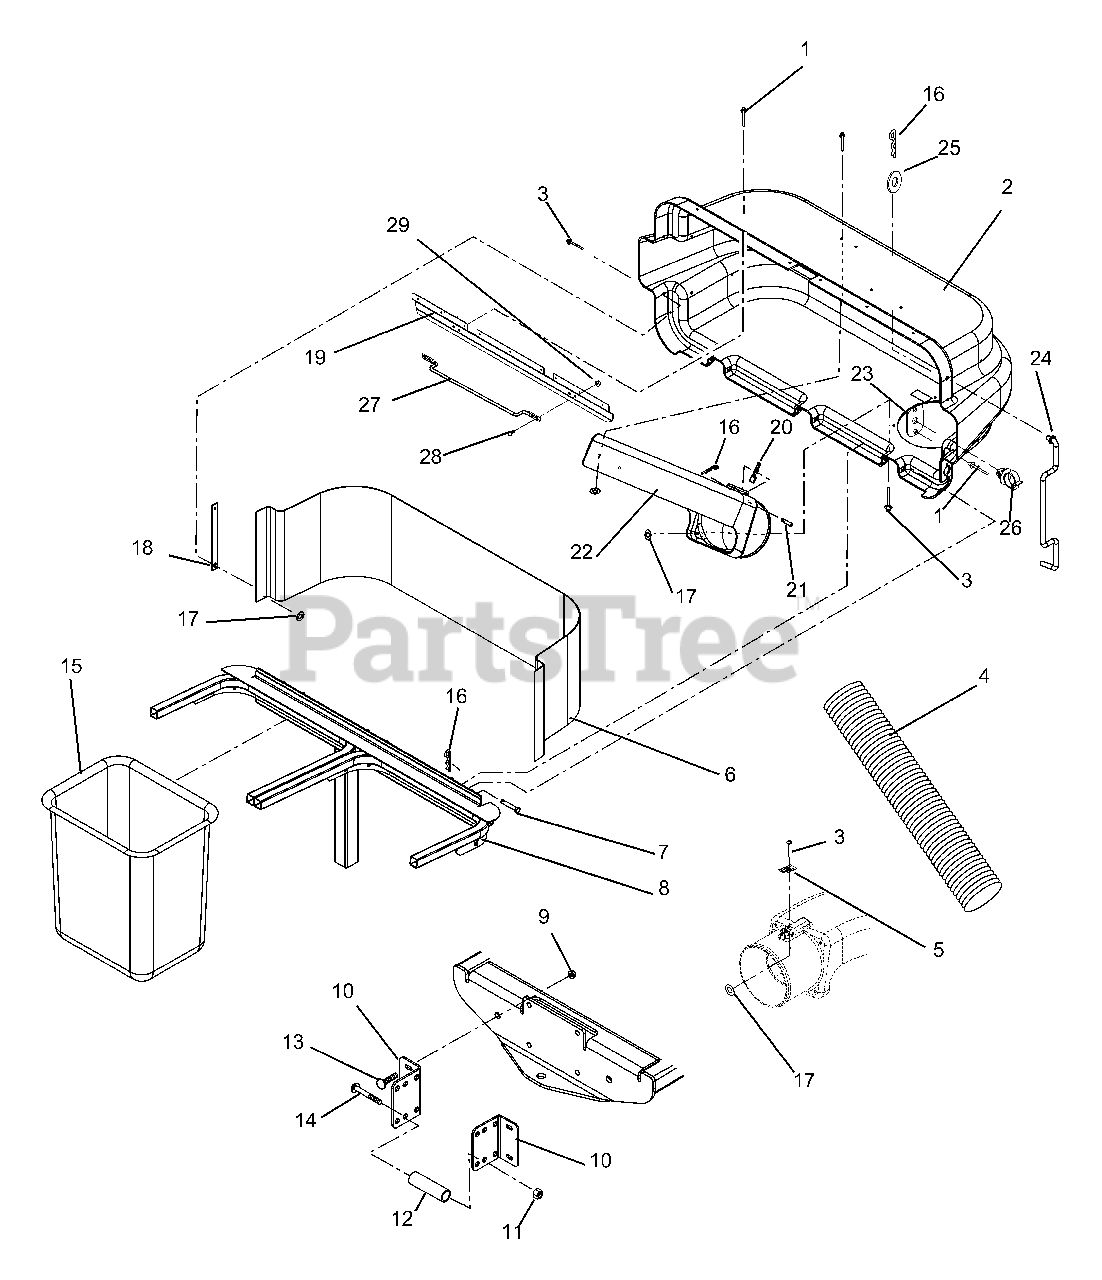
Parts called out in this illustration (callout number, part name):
1	RVT-POP .187X.402 DOME ST
2	BAGGER COVER W/DECAL
3	RVT-POP .187X.375
4	HOSE, FLEXIBLE-47"
5	THUMB LATCH
6	SCREEN, BAGGER
7	PIN-CLEV .371X3.25 YWZC
8	WMT,BAGGER FRAME
9	@NUT-LK-NYL-FLG .38-16 YWZC
10	BKT,BAGGER MOUNT
11	@NUT-LK-TOP-FLG .50-13 YWZC
12	SPACER, PIVOT .500X.750X1.805
13	@BLT-RDHDSQNK .38-16X1.25 G5YZ
14	@BLT-HEX .50-13X3.00 GR5 YWZC
15	GRASS BAGGER BASKET
16	PIN-HAIR, ENDRIES #25 YWZC
17	@WSHR-FL-STL.219X.50X.049 YWZC
18	STRAP,COVER
19	LATCH, BAGGER (MZ)
20	INDICATOR, FLOW
21	PIN-CLEV .309 X 1.625 YWZC
22	BOOT,UPPER
23	PLATE, ROD CLIP
24	PROP-ROD,BAGGER
25	@WSHR-FL-STL.406X.812X.065 YWZ
26	CLIP-.38
27	BAGGER HANDLE
28	@BLT-RDHDSQNK .25-20X.75 G5YZ
29	NUT-LUG .50-20 YWZC
